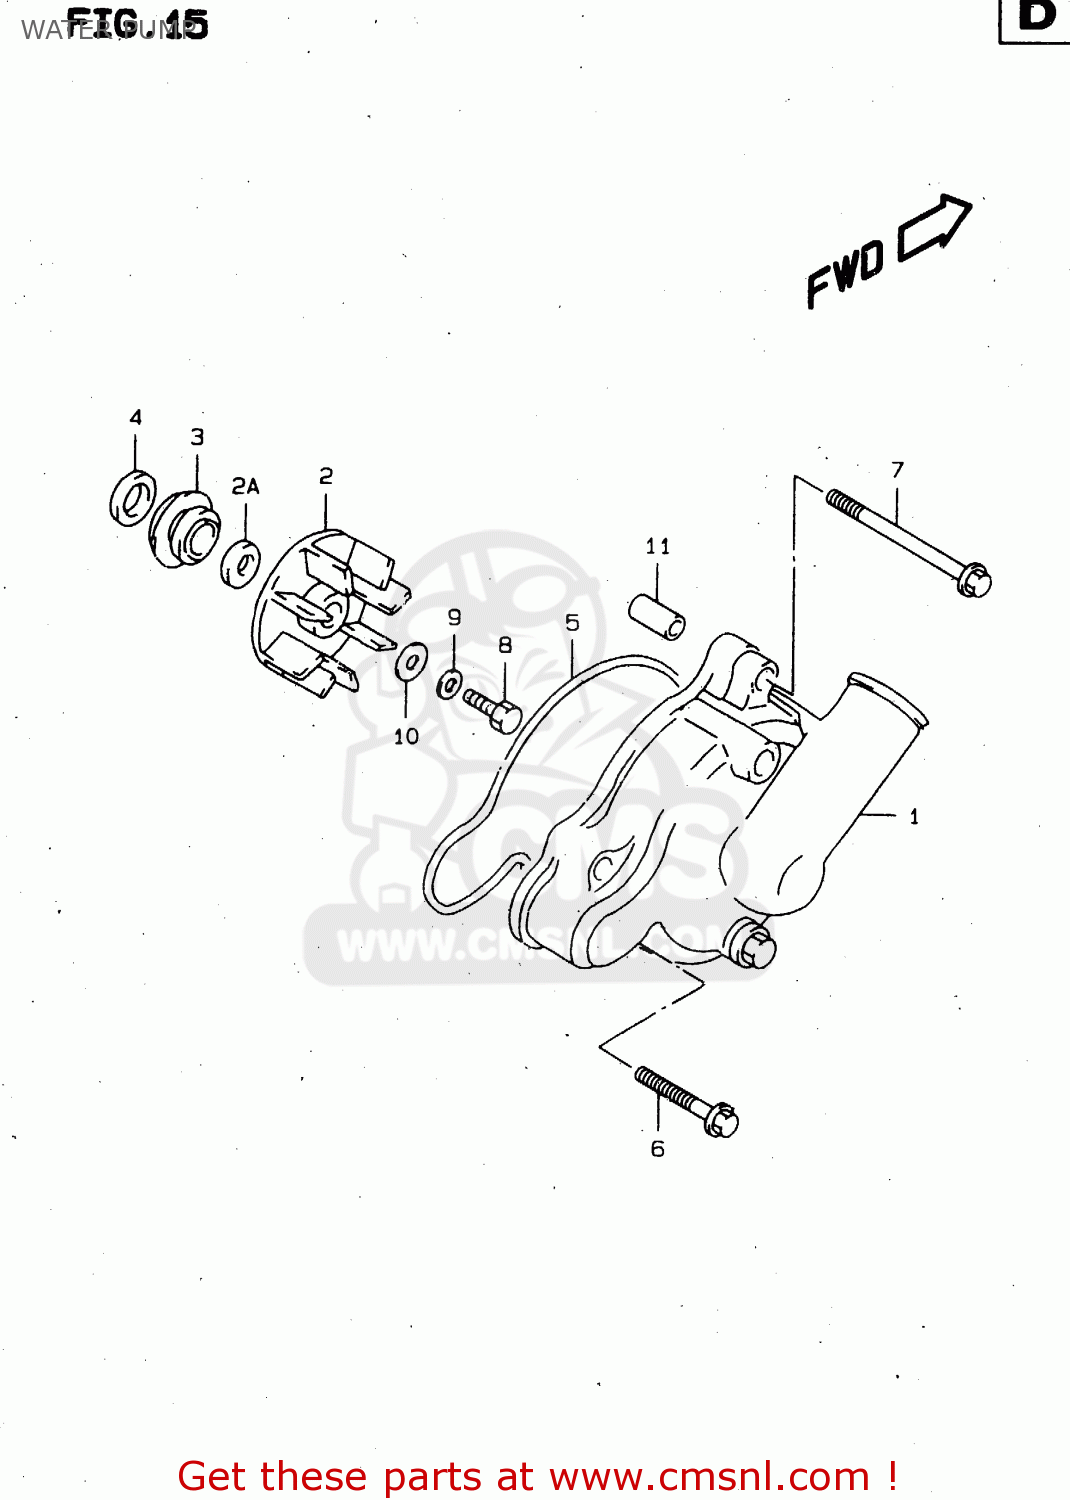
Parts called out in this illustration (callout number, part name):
1	CASE,WATER PUMP
2	IMPELLER,WATER PUMP
2A	WASHER,IMPELLER
3	SEAL,MECHANICAL
4	SEAL,OIL(10X20X5)
5	O RING,WATER PUMP CASE
6	BOLT
7	BOLT
8	BOLT(6X13)
9	WASHER
10	GASKET(6X15X2.2) (NAS)
11	PIN
